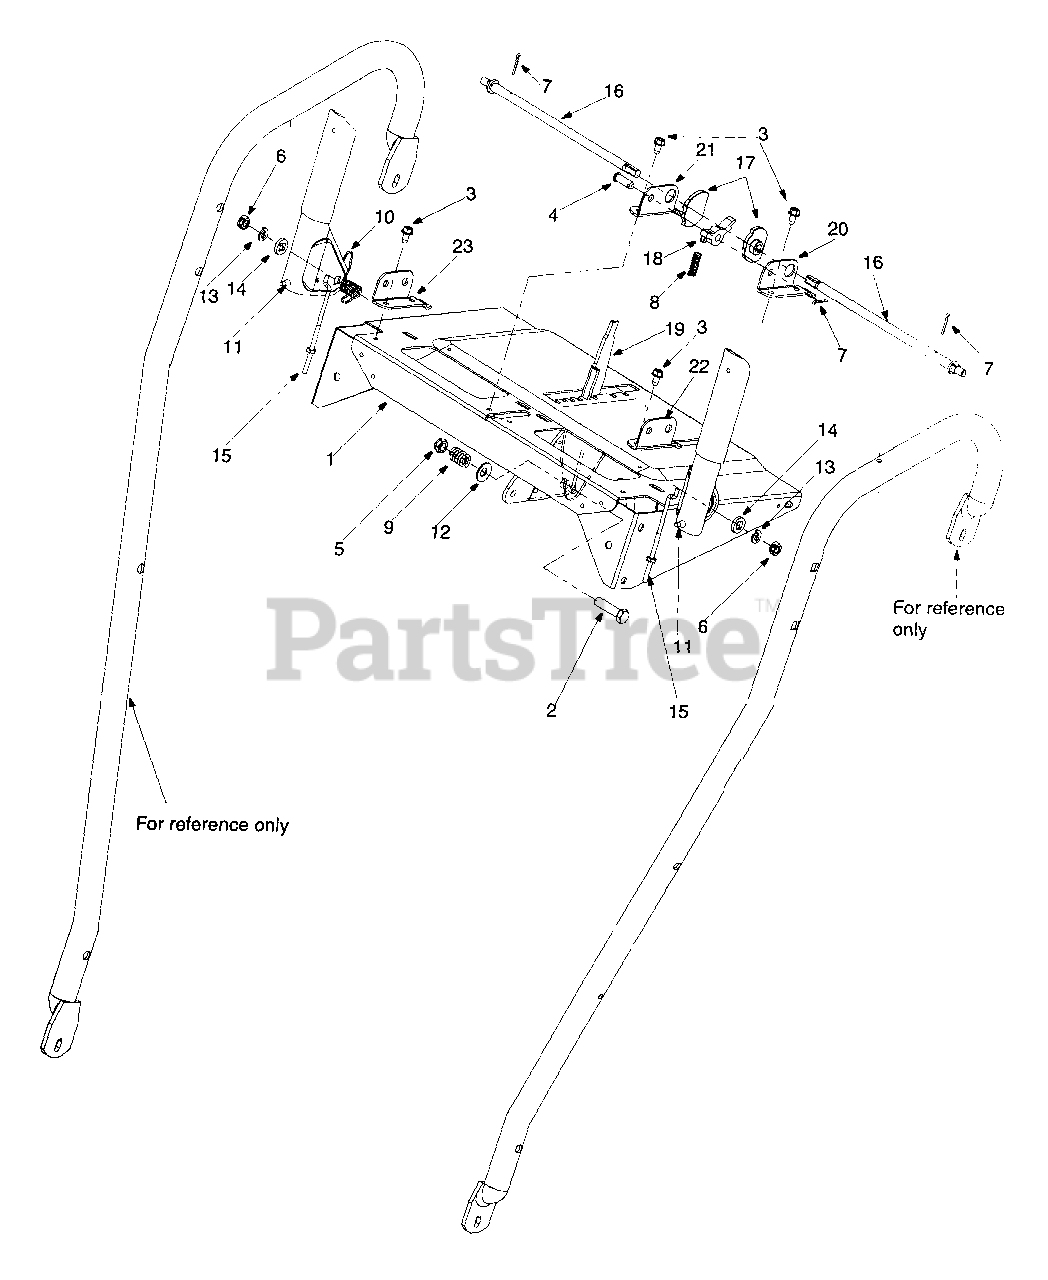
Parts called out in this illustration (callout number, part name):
2	Hex Bolt: 3/8-24 x 1.5 Gr.5
3	Hex Washer Head TT Screw: 1/4-20 x 0.5
4	Clevis Pin
5	Jam Nut
6	Hex Nut
7	Cotter Pin
8	Compression Spring
9	Compression Spring
10	Torsion Spring
11	Rubber Bumper
12	Bell Washer
13	Lock Washer
14	Special Washer
15	"Z" Fitting For Control Cables
16	Rod: Cam
17	Cam Handle Lock
18	Pawl: Handle Lock
